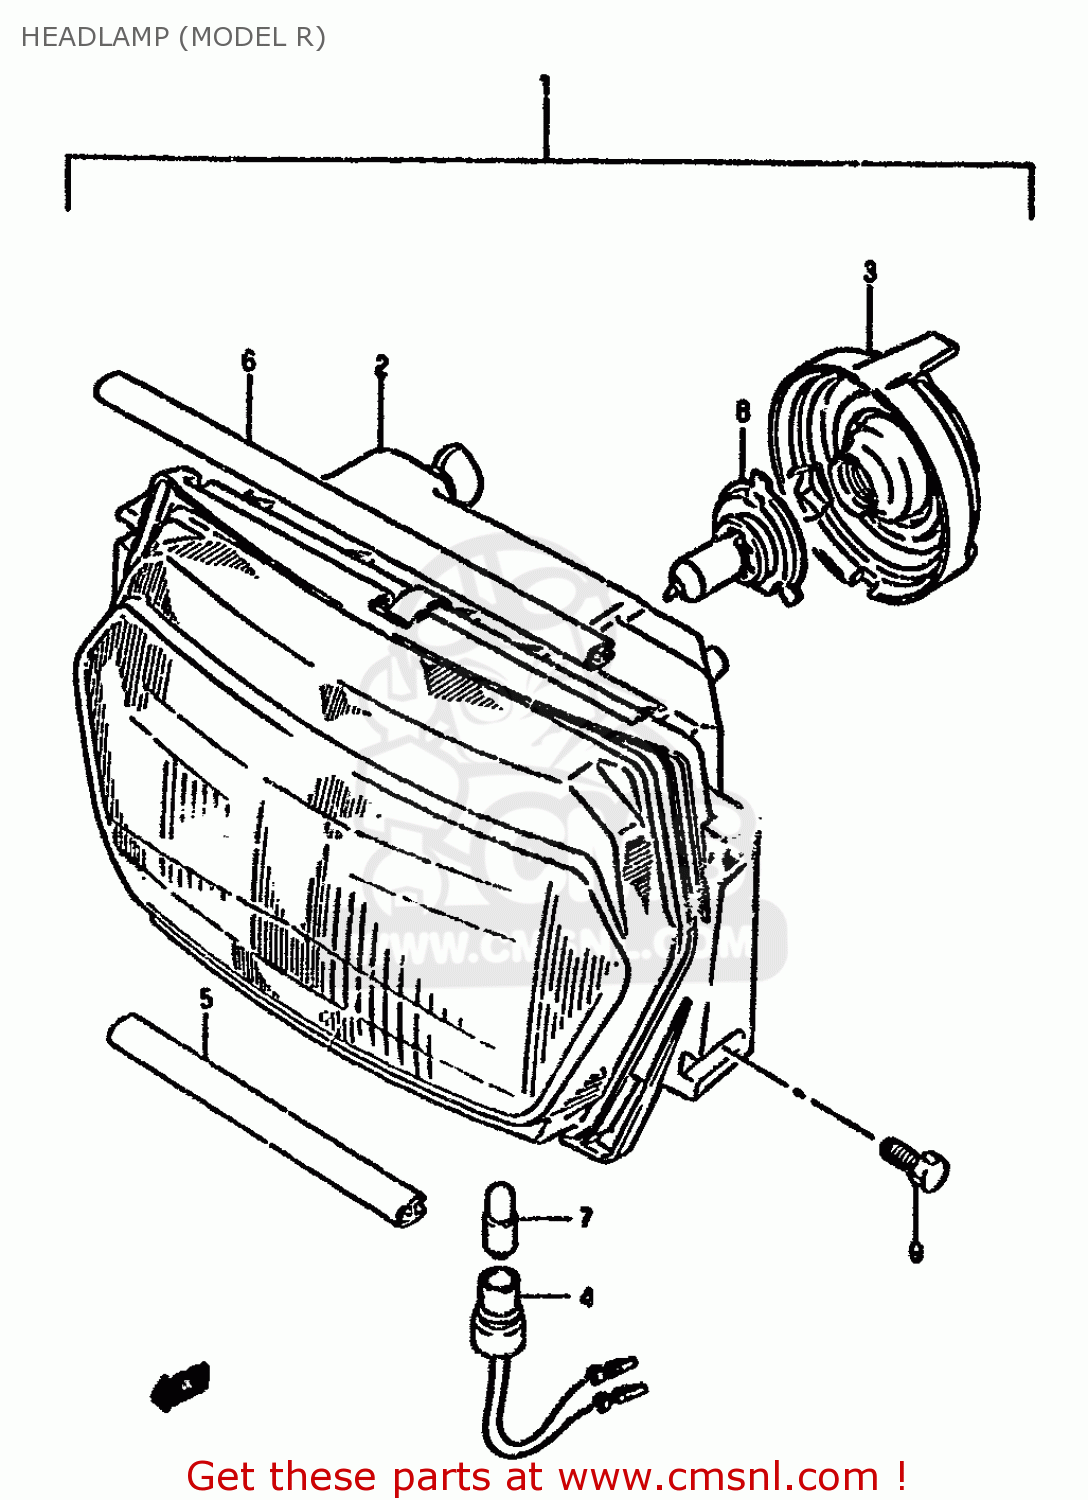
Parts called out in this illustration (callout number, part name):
1	HEADLAMP ASSY
2	UNIT
3	COVER,SOCKET
4	SOCKET
5	GASKET,HEADLAMP,LOWER (NAS)
6	GASKET,HEADLAMP,UPPER (NAS)
7	BULB(12V4W)
8	BULB(12V60/55W,H4)
9	BOLT
10	WASHER,LOCK
11	WASHER, LOWER
